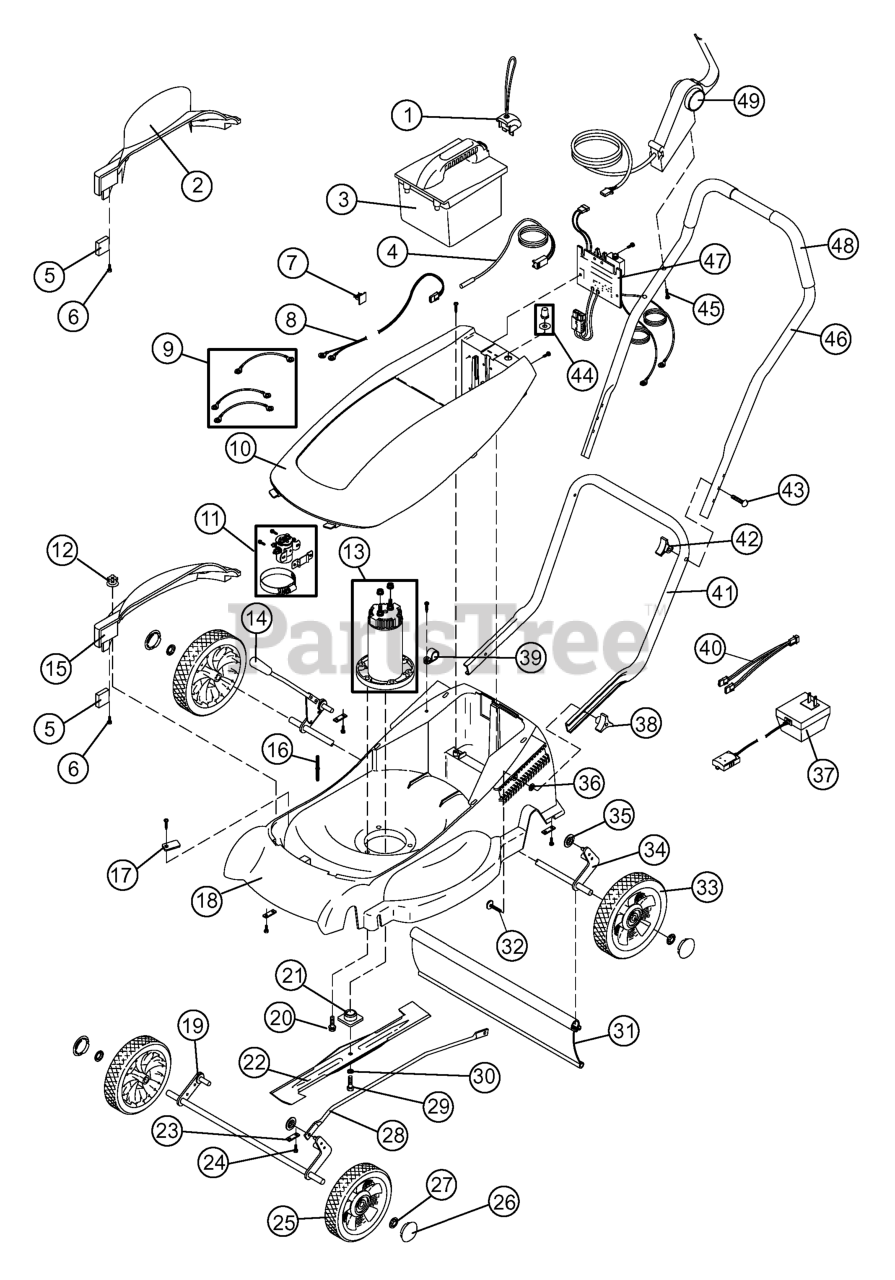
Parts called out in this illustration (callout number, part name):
1	Key Assembly *
2	Discharge Chute
3	Battery Pack Assembly
4	Interlock Switch Assembly *
7	Cord Clip
8	Circuit Board Wire Assembly
9	Harness - Wiring
10	Mower Cover *
11	Solenoid *
13	Motor *
14	Height Adjustor Handle
15	Mulching Cover
16	Chute Stud
17	Interlock Retainer
18	Mower Deck
19	Height Adjustor, Front
20	Bolt, Motor
21	Blade Adaptor
23	Axle Retainer
25	Front Wheel
26	Hubcap
27	Wheel Retainer
28	Height Adjustor Link
29	Blade Mounting Bolt
30	Washer, Split Ring
31	Trailing Shield
32	Lower Handle Bar Bolt
33	Rear Wheel
34	Height Adjustor, Rear
35	Link Retainer
36	Bolt Retainer
37	Charger
38	Handlebar Knob
39	Wire Clamp
40	Harness, Battery Charger *
41	Lower Handlebar
42	Handlebar Knob
43	Handlebar Bolt
44	Circuit Breaker Label/Boot
45	Handlebar Screw
46	Upper Handlebar
47	Motor Control *
48	Foam Grip
49	Blade Control Assembly
